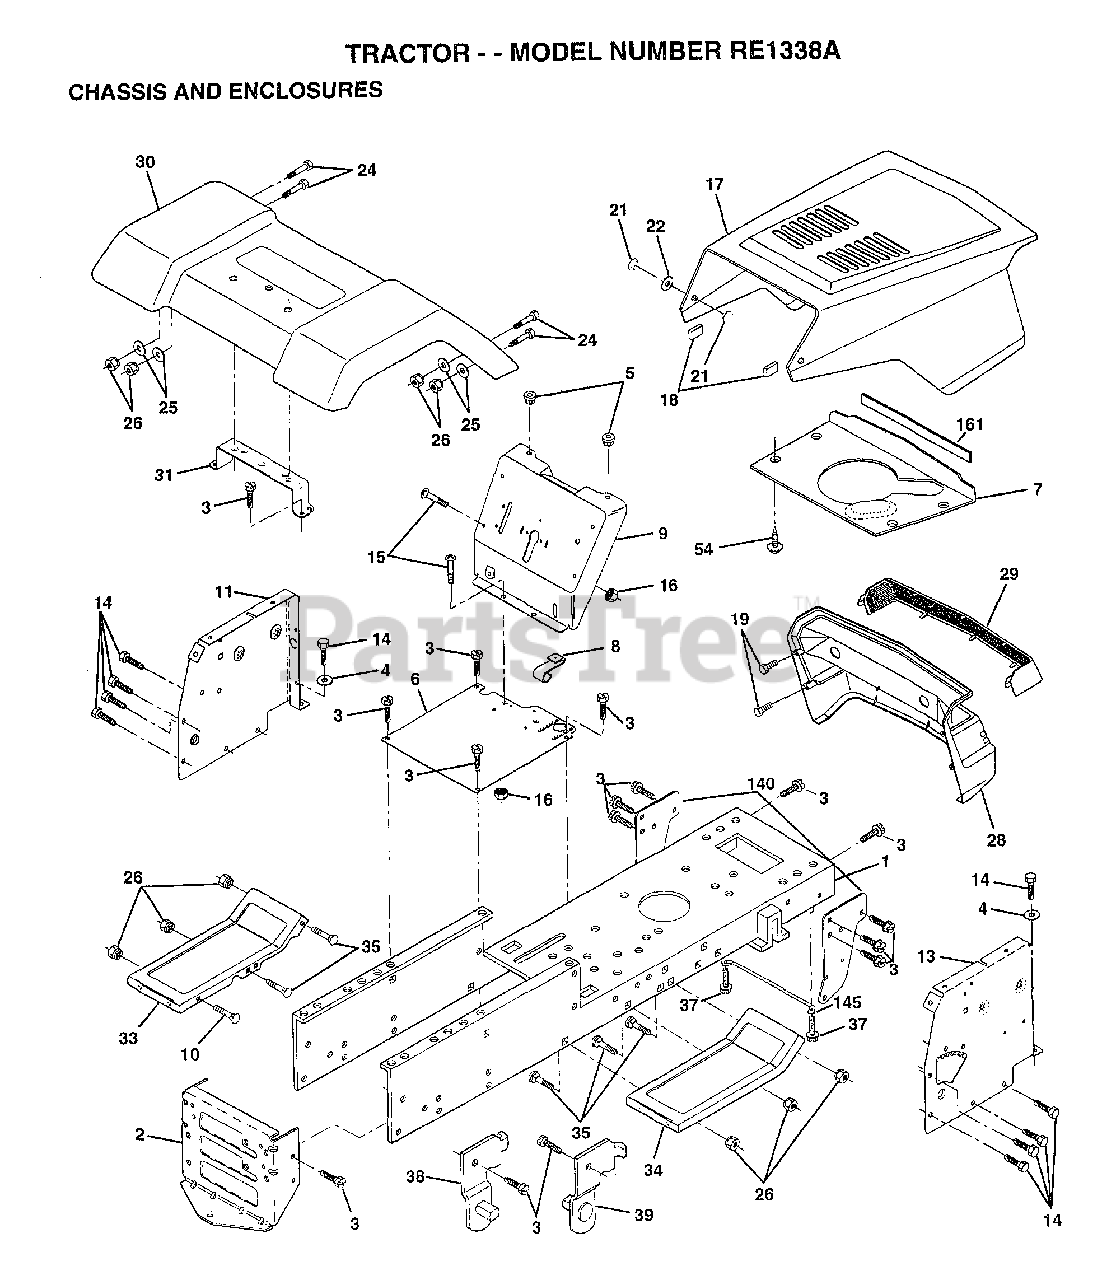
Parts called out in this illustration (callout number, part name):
1	CHASSIS.STAMPING
3	SCREW
4	WASHER
5	BUMPER-HOOD/DASH
6	SADDLE
8	CLIP.RETAINER
11	"PANEL-DASH,LH"
14	SCREW LT
15	SCREW
17	HOOD/GRILLE ASM
19	"SCREW,HWHD.HI-LO#13-16X3/4"
21	"RIVET,PLASTIC"
24	BOLT
25	WASHER
26	NUT
29	LENS HEADLIGHT
30	FENDER.LT.W/SHIFT
31	BRKT FENDER
33	FOOTREST LH
34	FOOTREST RH
35	BOLT
37	SCREW LT
38	BRACKET ASM LH
39	BRACKET ASM RH
54	SCREW.HEX.WS.HD
140	BRKT SUSPENSION
145	"ROD POVOT,CHASSIS"
161	EXTRUSION HOOD
